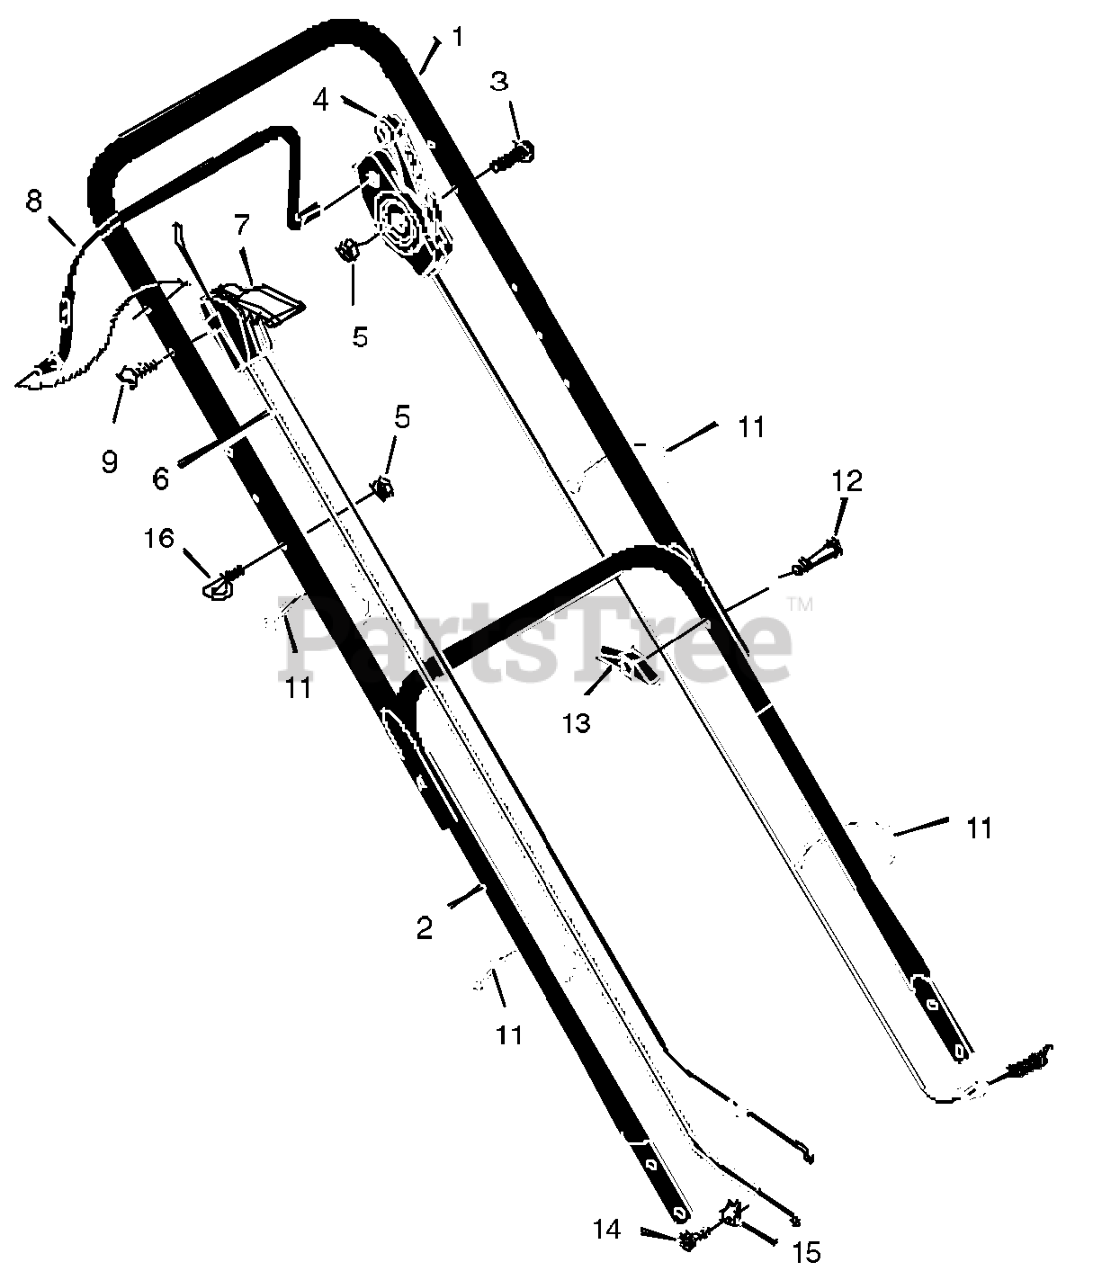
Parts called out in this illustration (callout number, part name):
1	Handle, Upper (Black)
2	Handle, Lower (Black)
4	Control, Drive
5	Locknut
6	Cable, Stop
7	Throttle Control
8	Lever, Stop
11	Fastener, Cable
13	Knob
16	GUIDE, ROPE
